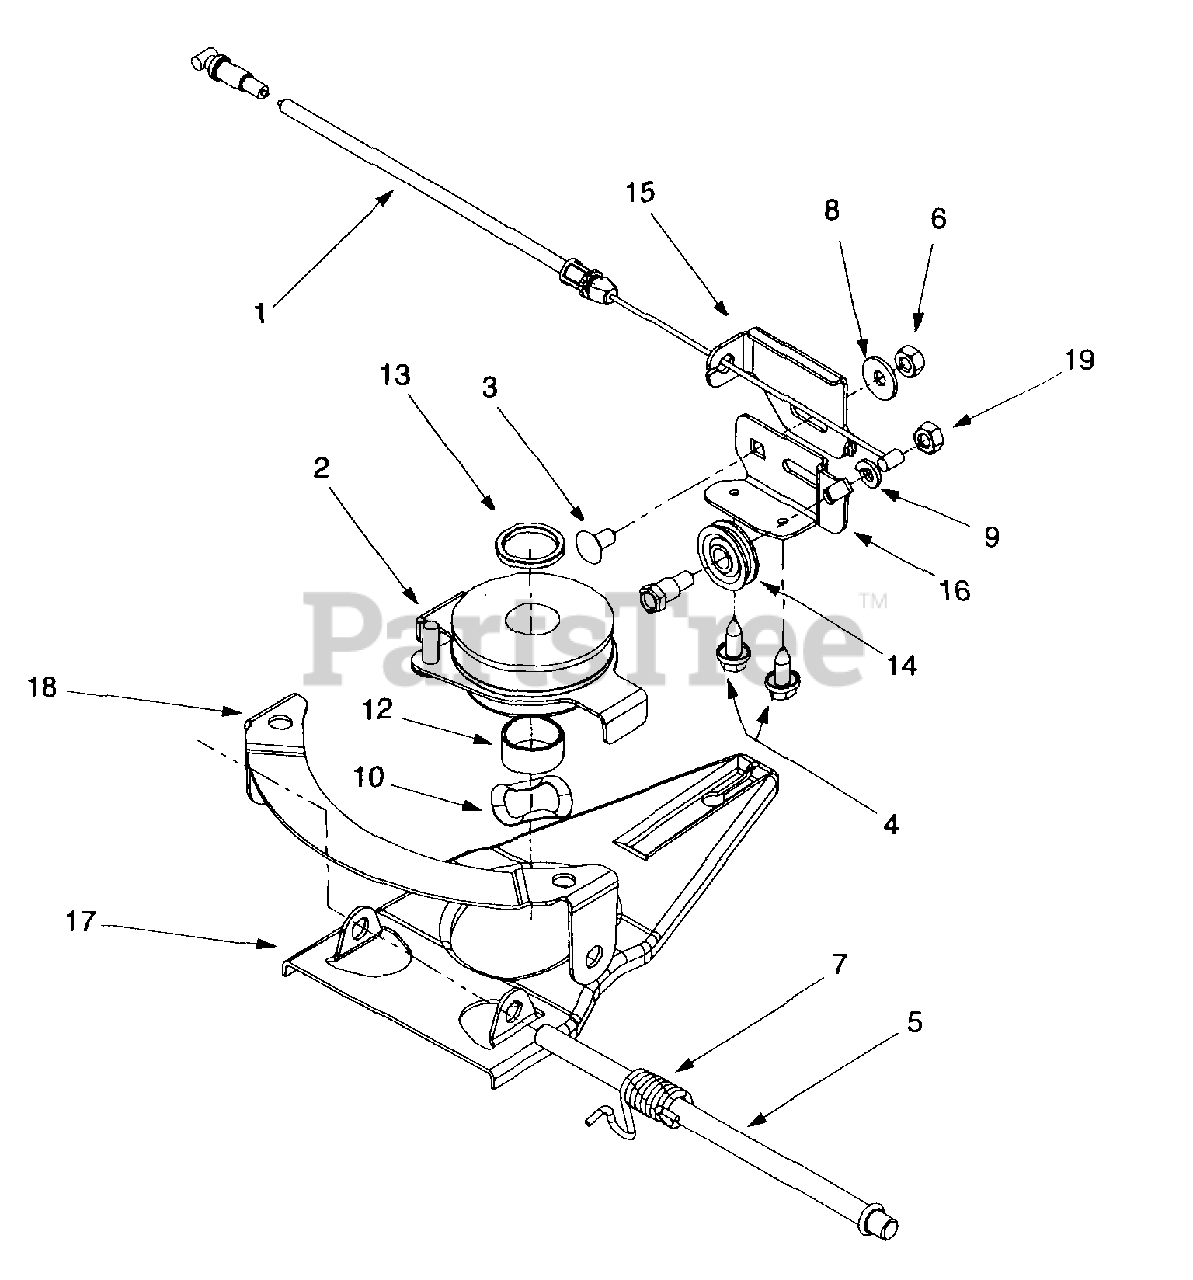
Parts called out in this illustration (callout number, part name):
1	Speed Selector Cable, 53"
2	Multi-speed Pulley Assembly
3	Carriage Bolt, 1/4-20 x. 5
4	Self-tapping Screw, 1/4-20 x .625
5	Pivot Shaft
6	Nut, 1/4-20
7	LH Torsion Spring
8	Bell Washer, .265 x .75 x .062
9	Lock Washer, 1/4
10	Wave Washer, 1.38 x .88 x .029
12	Sleeve Spacer, .88 ID x 1 OD x .48
13	Sleeve Spacer, .88 ID x 1.13 OD x .12
14	Cable Roller
19	Hex Nut, 1/4-20
